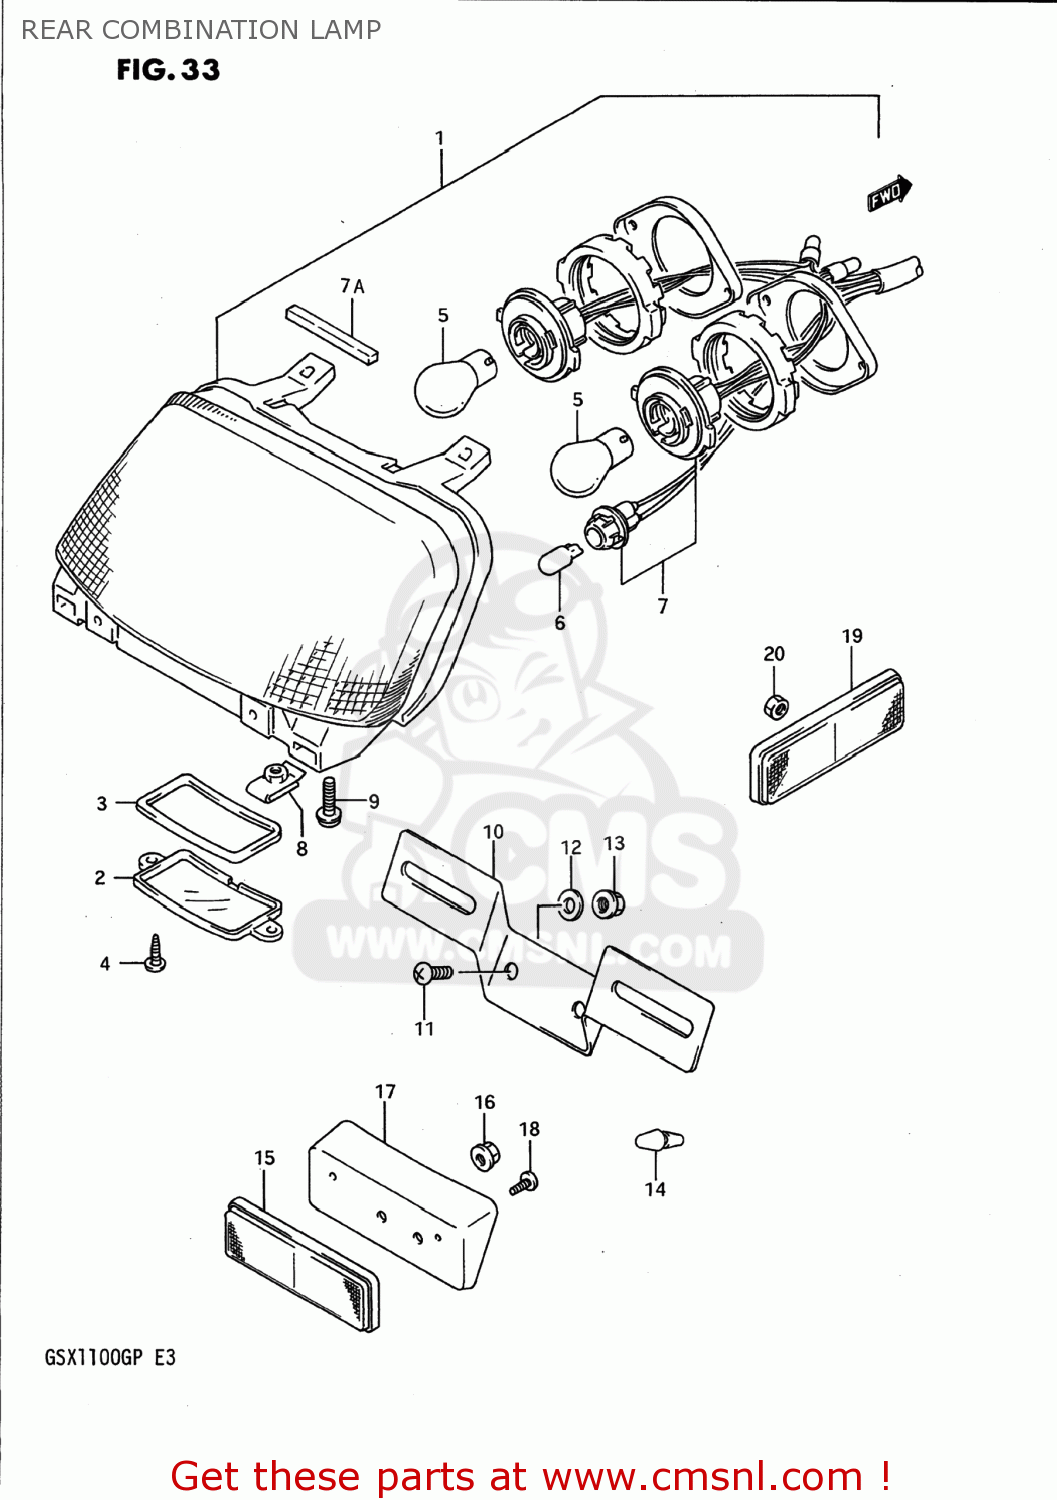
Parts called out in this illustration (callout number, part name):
1	LAMP ASSY,RR COMBINATION
2	LENS,LICENSE
3	GASKET (NAS)
4	SCREW
5	BULB(12V21/5W)
6	BULB(12V5W)
7	CORD ASSEMBLY
7A	CUSHION,HANDLE COVER
8	NUT,HEADLAMP HOUSING,UPPER
9	SCREW
10	BRACKET,LICENSE PLATE
11	SCREW
12	WASHER (6.3X14X1.6)
13	NUT
14	CUSHION
15	REFLECTOR ASSEMBLY,REAR
16	NUT
17	SPACER,RR RR
18	SCREW
19	REFLECTOR ASSEMBLY,REAR
20	NUT
